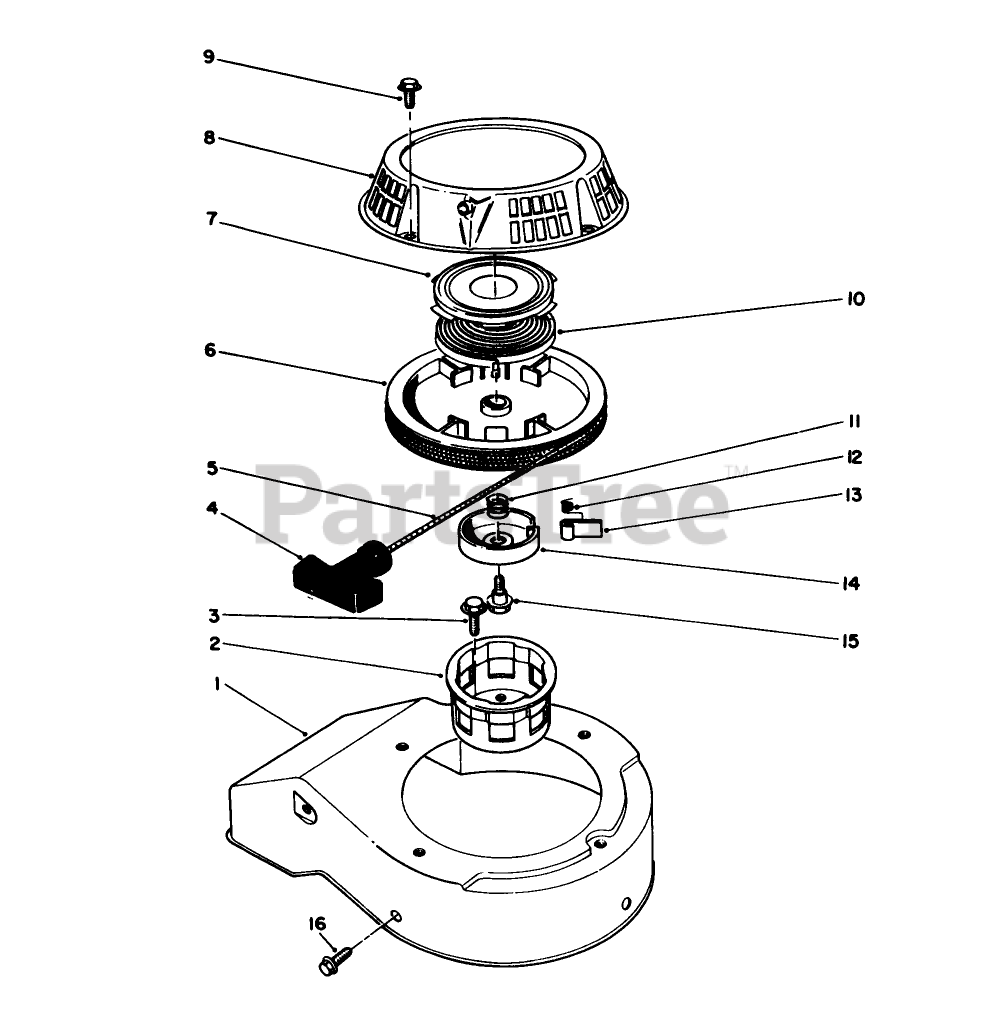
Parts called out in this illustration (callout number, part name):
1	Cover-Cooling Fan
2	PULLEY-CUP, STARTER
4	HANDLE-RECOIL
5	ROPE-STARTER
7	Retainer-Spring, Recoil
8	CASE-STARTER
9	SCREW-HHF
10	Spring-Recoil
11	SPRING
12	SPRING
14	RETAINER
